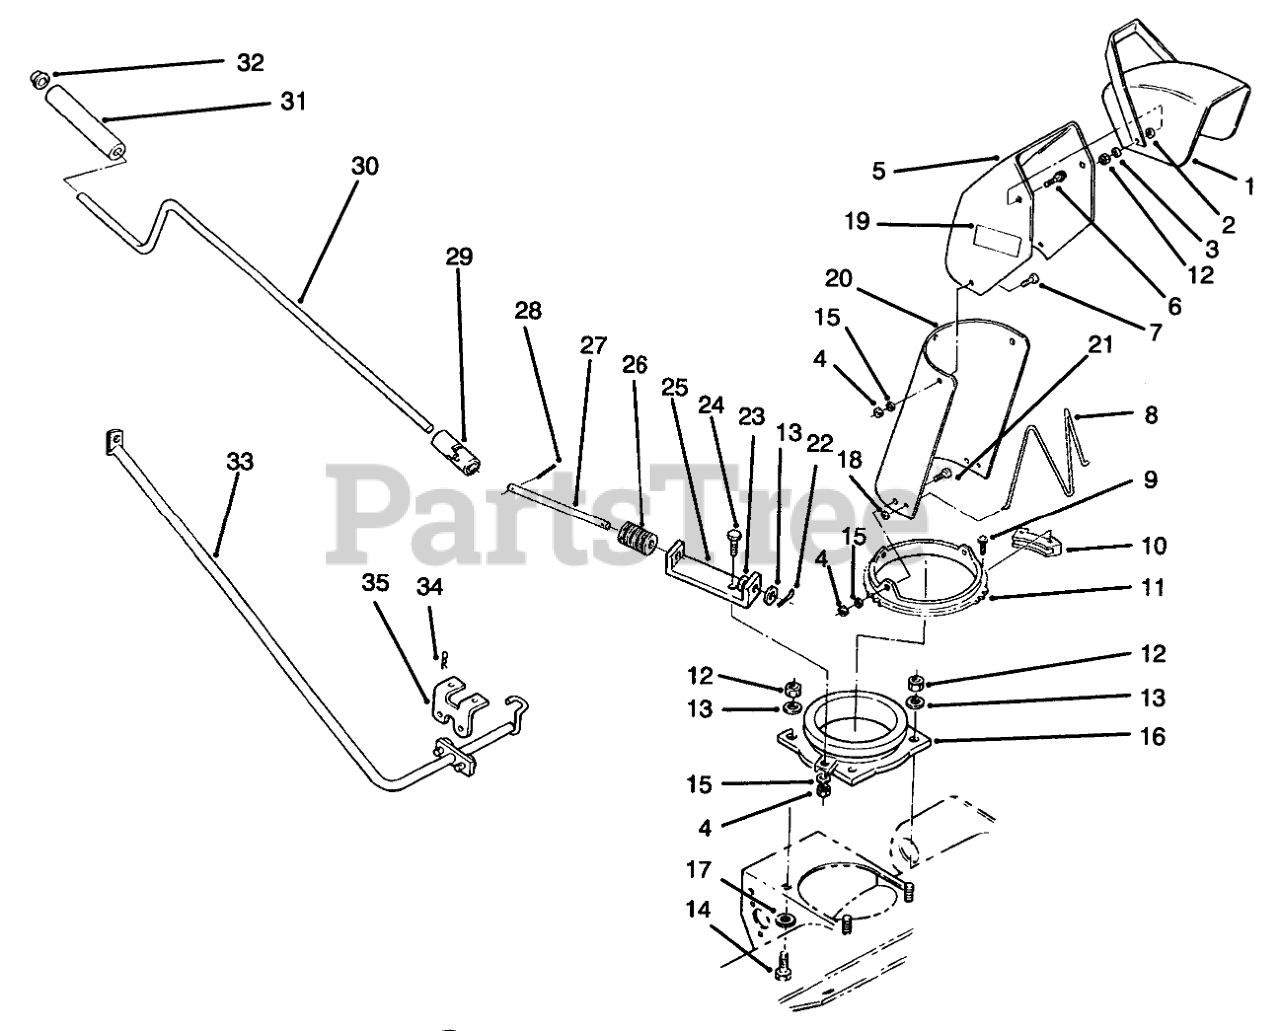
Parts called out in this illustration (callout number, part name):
1	DEFLECTOR/DECAL BLACK
2	WASHER-RUBBER
3	WASHER-BELLEVILLE
4	NUT-LOCK, NI
5	Chute-Discharge (Incl. Ref. #19)
6	BOLT-CARR
7	SCREW-HH
8	WIRE-CHUTE
9	SCREW-SPECIAL
10	RETAINER-CHUTE
11	RING-CHUTE SWIVEL
12	NUT-LOCK, NI
13	WASHER-FLAT
14	SCREW-HH
15	WASHER-PLAIN
16	ADAPTER
17	Washer
18	NUT-PUSH
19	Decal-Danger
20	EXTENDER-CHUTE, UPPER
21	BOLT-CARR
22	PIN-COTTER
23	WASHER-SPRING
24	BOLT-CARR
25	BRACKET-WORM
26	GEAR-WORM, CHUTE
28	PIN-SPRING
29	Universal
30	ROD-CHUTE CONTROL
31	GRIP-CONTROL, CHUTE
32	RETAINER-PUSH ON
33	SUPPORT
34	Hairpin Cotter
35	BRACKET
